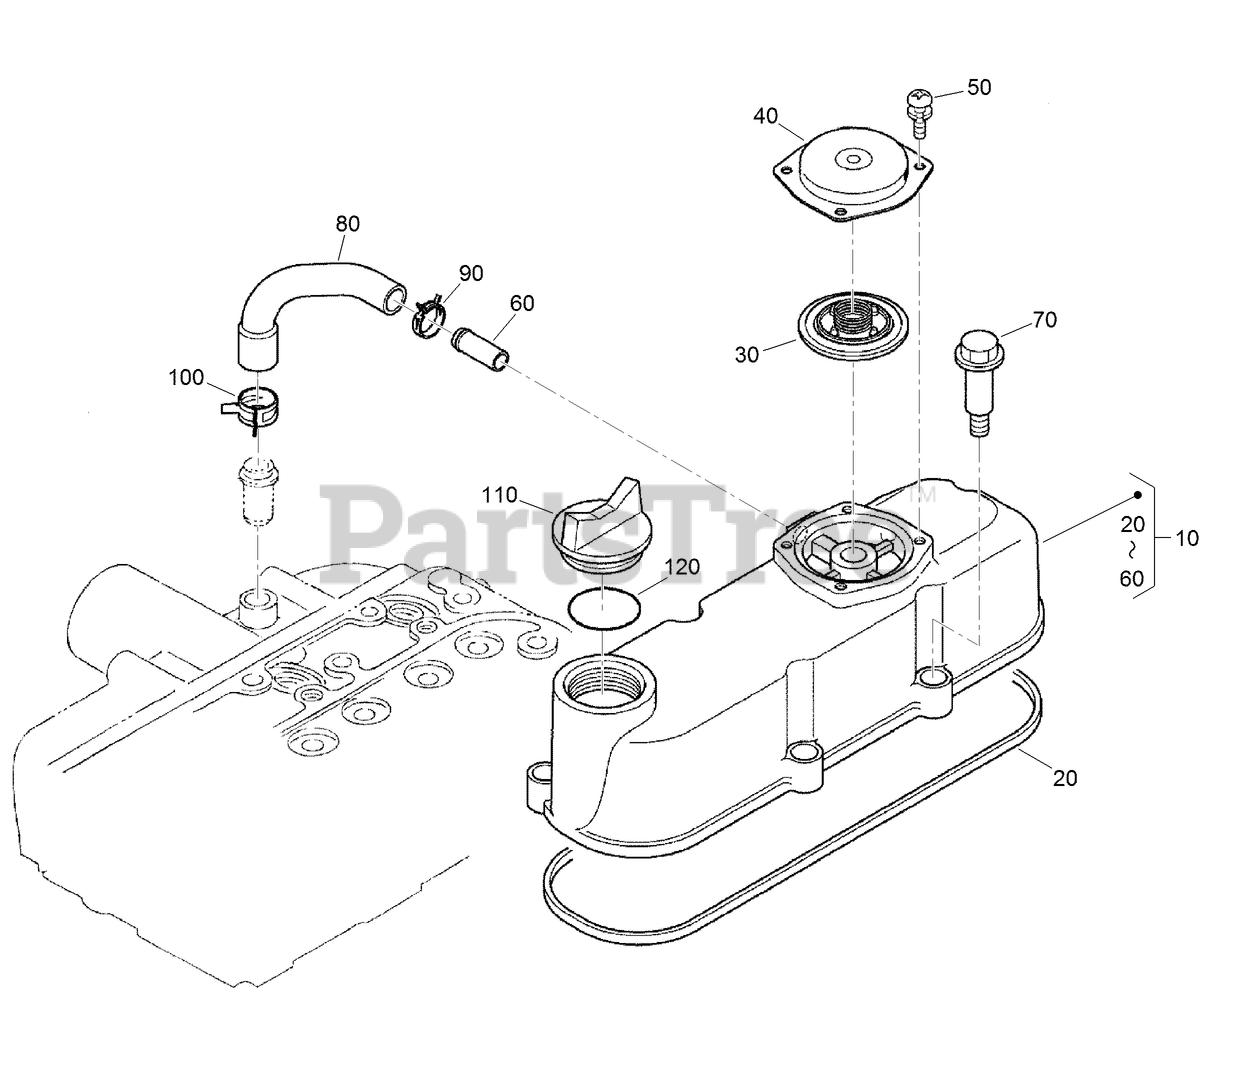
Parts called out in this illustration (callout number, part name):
10	CYLINDER HEAD COVER ASM
20	GASKET-COVER, HEAD
30	VALVE-BREATHER
40	COVER-BREATHER
50	SCREW (WITH WASHER)
60	PIPE-RETURN, WATER
80	TUBE-BREATHER
90	CLAMP-HOSE
100	CLAMP-HOSE
110	PLUG-FILLER, OIL
120	O-RING
